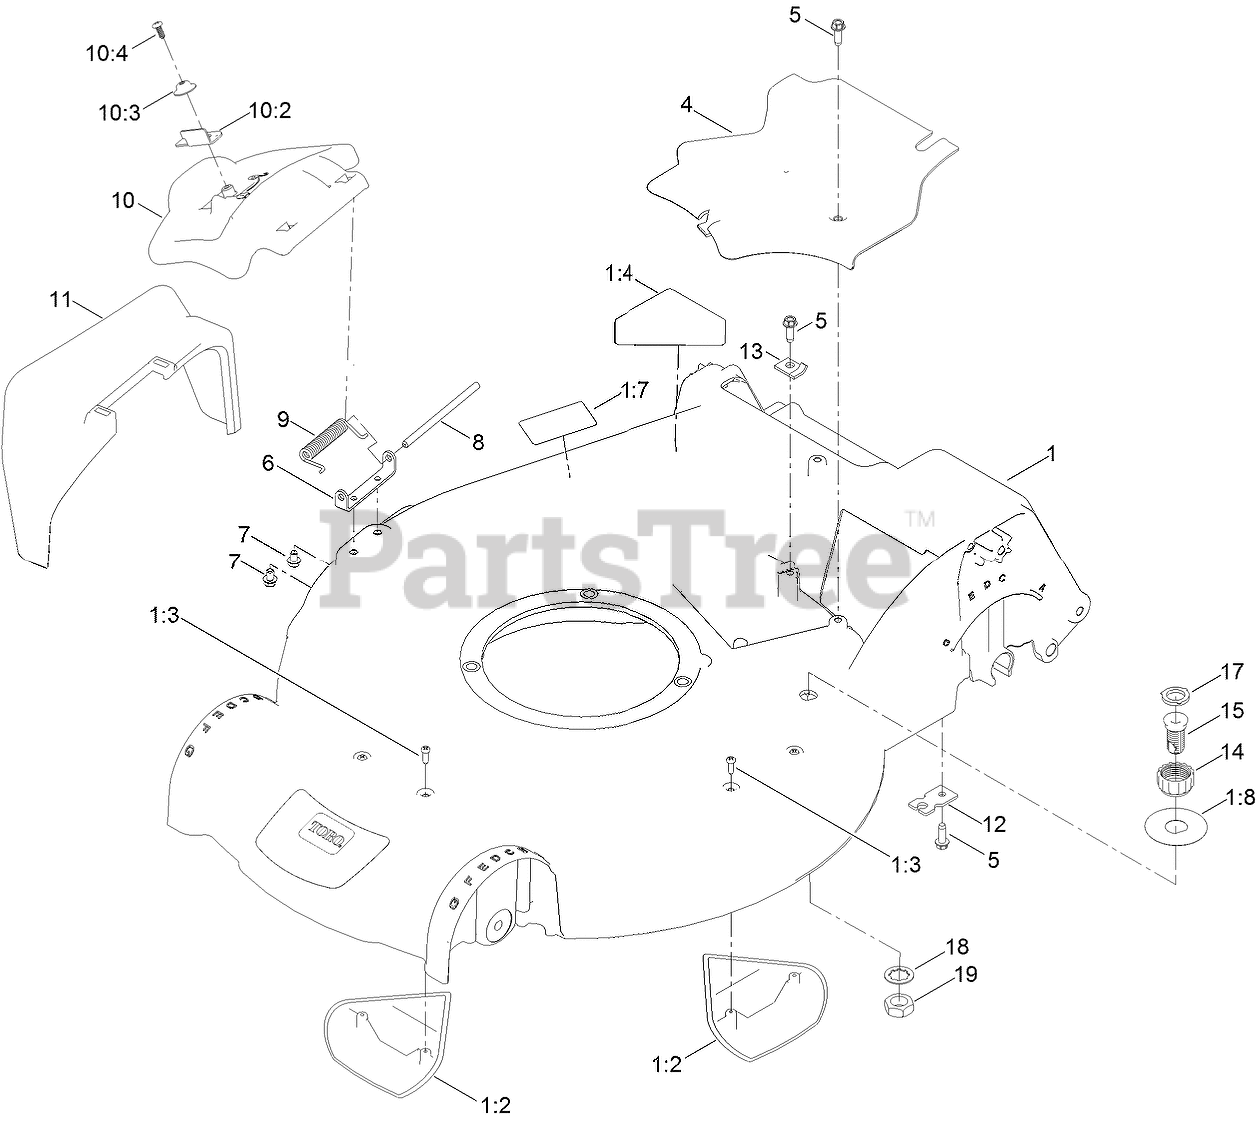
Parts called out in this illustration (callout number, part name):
1	HOUSING ASM
1:2	KICKER-HOUSING
1:3	SCREW-PPH
1:4	DECAL-DANGER
1:7	DECAL-PLACEMENT, FOOT
1:8	DECAL-QUICK WASH
4	COVER-BELT
5	SCREW-HWHTF
6	BRACKET-COVER
9	SPRING-TORSION
10	DISCHARGE DOOR ASM
10:2	LATCH-DOOR
10:3	CAP-DOOR
10:4	SCREW-PPH
11	CHUTE-DISCHARGE, SIDE
12	BRACKET-CABLE, TRACTION
13	CLAMP-CABLE
14	COUPLING-HOSE, WASHOUT PORT
15	PORT-WASHOUT
17	WASHER-SEAL, WASHOUT PORT
18	WASHER-LOCK
19	NUT-JAM
